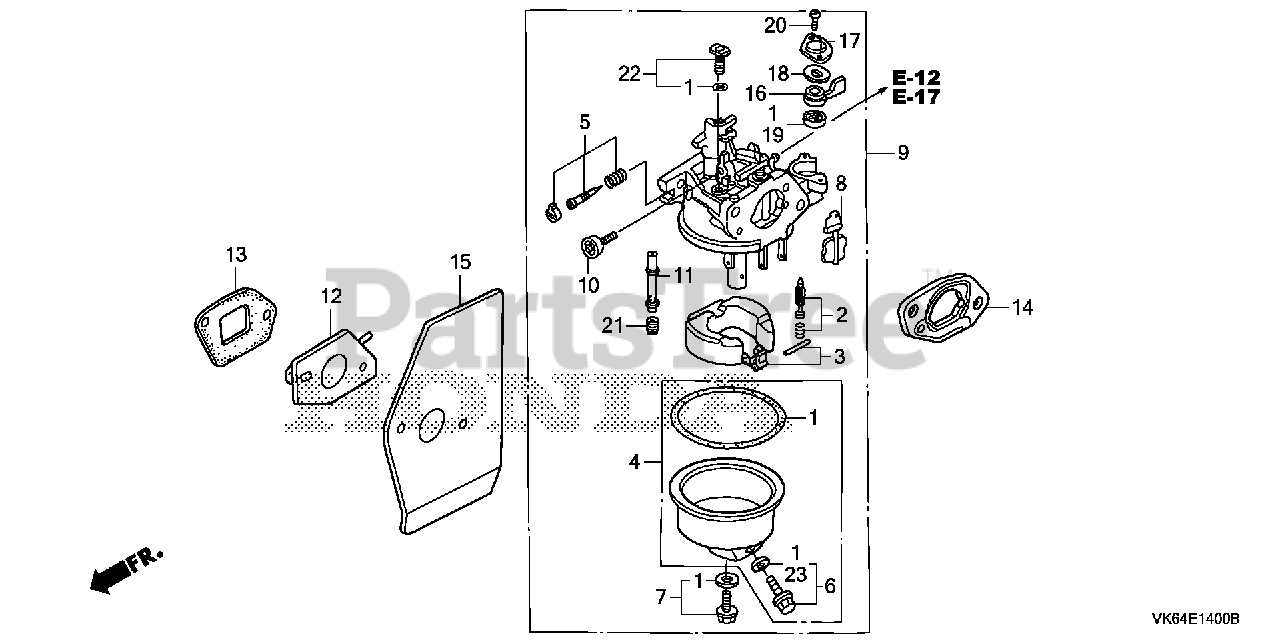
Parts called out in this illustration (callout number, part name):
1	GASKET SET
2	VALVE SET, FLOAT (SEAT NOT INCLUDED)
4	CHAMBER SET, FLOAT
5	SCREW SET, PILOT
6	SCREW SET, DRAIN
7	SCREW SET
9	CARBURETOR ASSY. (BE66N A)
10	SCREW, THROTTLE STOP
11	NOZZLE, MAIN
12	INSULATOR, CARBURETOR
13	GASKET, INSULATOR
13	GASKET, INSULATOR (NINGBO SIL GASKET)
14	SPACER, CARBURETOR
15	GASKET, CARBURETOR
15	GASKET, CARBURETOR (NINGBO SIL GASKET)
16	LEVER, PETCOCK
17	PLATE, LEVER SETTING
18	SPRING, PETCOCK LEVER
19	GASKET, PETCOCK
20	SCREW, PAN (3X6)
21	JET, MAIN (#62)
21	JET, MAIN (#65)
21	JET, MAIN (#68)
22	JET SET, PILOT (#35)
23	WASHER, PLAIN (6.2X10.7 DRAIN)
